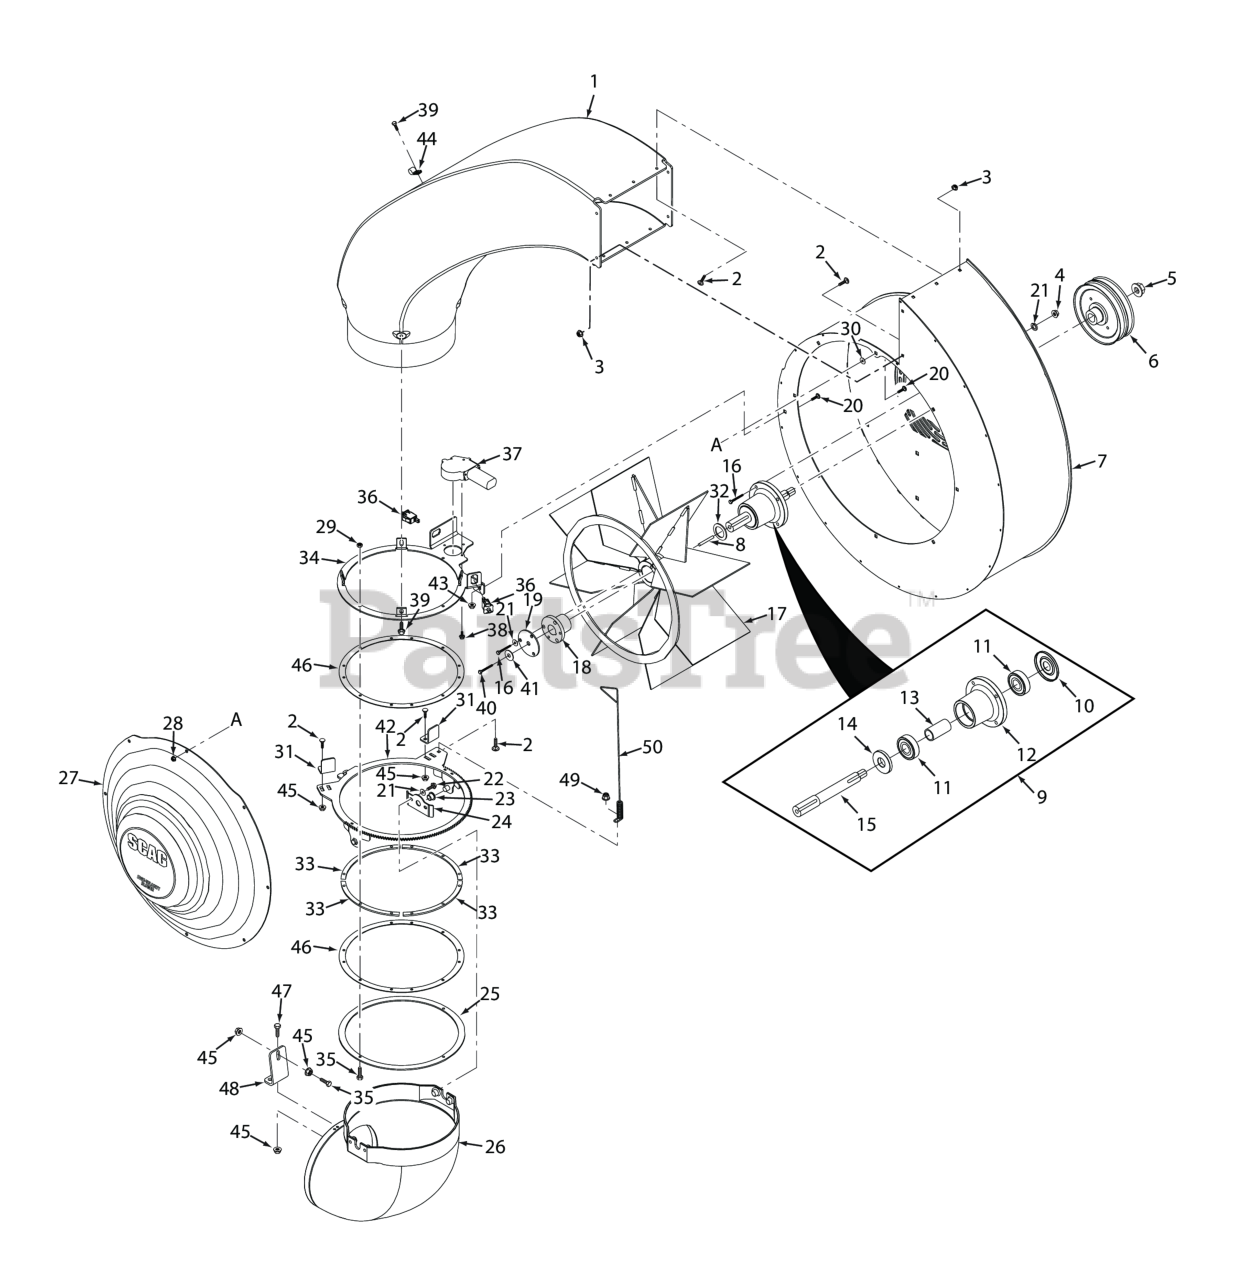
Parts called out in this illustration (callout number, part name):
1	Outlet Adapter, Impeller Housing
2	Serr. Fl. Hex Head CPSCR, 1/4-20 x 3/4"
3	Nut, Flanged Elastic Stop 1/4-20
4	Lock Nut, 5/16-18 Elastic Stop Grade 8
5	Nut, 3/4-16 Spriral Lock
6	Pulley, Blower, 6.95 DIA, Double Groove
7	Blower Housing, With Decal
8	Key, 1/4 x 1/4 x 2.0"
9	Spindle Assembly (INCL. 10,12,14,15)
10	Debris Shield
11	Bearing
12	Spindle Housing Assembly
13	Spacer, Bearing
14	Protector, Bearing
15	Shaft, Spindle
16	Bolt, Hex Head 5/16-18 x 1-1/2" Grade 8
17	Impeller Weldment
18	Bushing, Split Taper 1.125 Bore
19	End Plate, Tapered Hub
20	Bolt, 5/16-18 x .75 RHSN Carriage
21	Lockwasher, 5/16 (.317 x .586 x .078) Helical Spring
22	Bolt, Hex Head 1/2-13 x 1.5"
23	Bearing, Plastic
24	Brace Plate, Nozzle Pivot
25	Bottom Plate, Pivot Gear
26	Outlet Nozzle, Impeller Housing
27	Baffle Weldment, Intake, With Decal
28	Nut, Serrated Flange 5/16-18 (Right Front Engine Mounting, Briggs and Kohler Only)
29	HEX, NUT, ELASTIC STOP LOCK, 1/4-20
30	Nut, Push-On 5/16-18
31	Stop Bracket, Nozzle Limit Switch
32	Flatwasher, 1" (1.062 x 1.50 x .048")
33	Bearing Plate, Pivot Gear
34	Top Plate, Pivot Gear
35	SERR. FLG. HEX HEAD CAPSCREW, 5/16-18 X 3/4
36	Switch, Plunger, Double Pole, Snap
37	Motor, Gear Drive
38	HHCS, M5-.8 X 10 SERR FLG
39	CAP SCREW, 5/16-18 X 1/2" SERRATED FLANGE HEX
40	Bolt, Hex Head 7/16-20 x 1"
41	Lockwasher, 7/16� Spring
42	Pivot Gear, Nozzle
43	Nut, Flange Head Elastic Stop 5/16-18
44	Clamp, Cable 1/2" I.D.
45	NUT, 1/4-20 SERRATED FLANGE HEX HEAD
46	Wear Disc, Pivot Gear
47	BOLT, HEX HEAD, 1/4-20 X 3/4 GR.5
48	Bracket, Nozzle Tilt
49	Nut, Flanged Elastic Stop 1/4-20
50	Directional Flag, Nozzle
